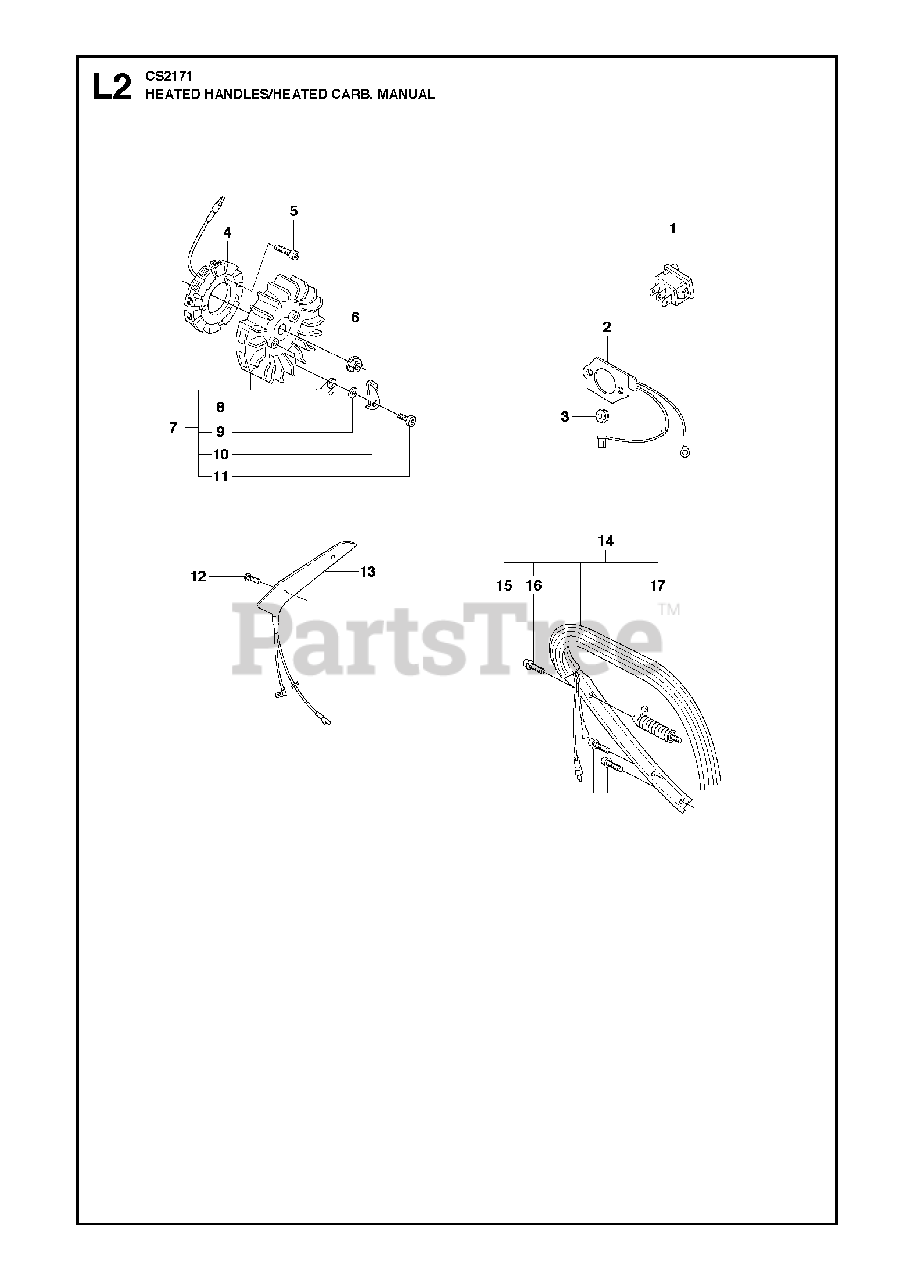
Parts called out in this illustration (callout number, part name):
2	FOIL ELEMENT
4	GENERATOR
6	NUT W/ WASHER
7	FLY WHEEL
8	SPRING
9	WASHER
10	PAWL
11	SCREW M5X14
13	PLATE (G)
14	FRONT HANDLE
15	SCREW
16	SCREW
17	ANTIVIBE MOUNT
